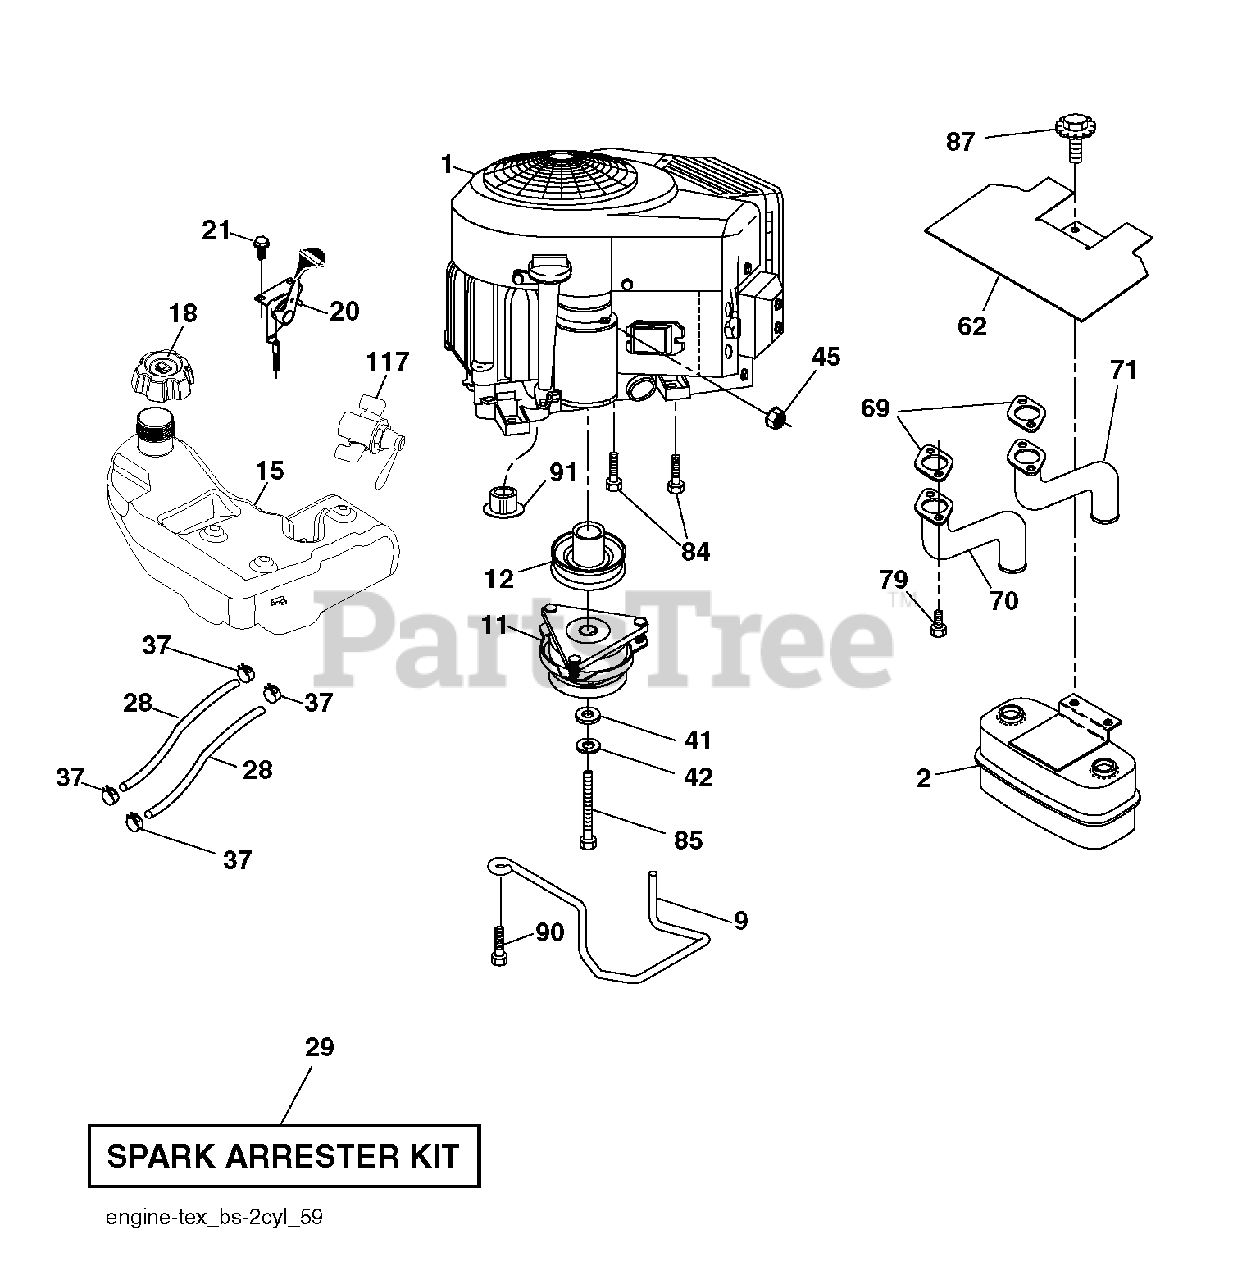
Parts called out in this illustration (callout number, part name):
1	Husqvarna TBD
2	MUFFLER.TWIN.CYL.LOW.TONE
9	KEEPER.BELT.ENGINE.4.2
11	CLUTCH.ELECTRIC.LT.48"*
12	PULLEY.ENGINE.TUFFTORQ
18	RP CAP FUEL
20	CONTROL.TH/CK.COBRA.B&S.TWN.
21	SCREW.#10 X 0.750.BOS
28	REPL BY 532 00 85-43
29	KIT.SPARK ARRESTOR 794945 B&S
37	HOSE CLAMP
42	LOCKWASHER
45	NUT
62	SHIELD.HEAT.MUFFLER
69	GASKET.MUFFLER
70	RP.EXHAUST.TUBE.LH.BS/TWIN
71	EXHAUST.TUBE.RH.BS/TWIN
79	SCREW.SOCKET.HEAD.5/16-18
84	SCREW.3/8-16
85	BOLT HEX 7/16-20X4-1/4"
87	Bolt, 5/16-18 X 1-3/4
90	SCREW 3/8-16X1
91	BUSHING.1.375OD
117	VALVE FUEL RESERVE
